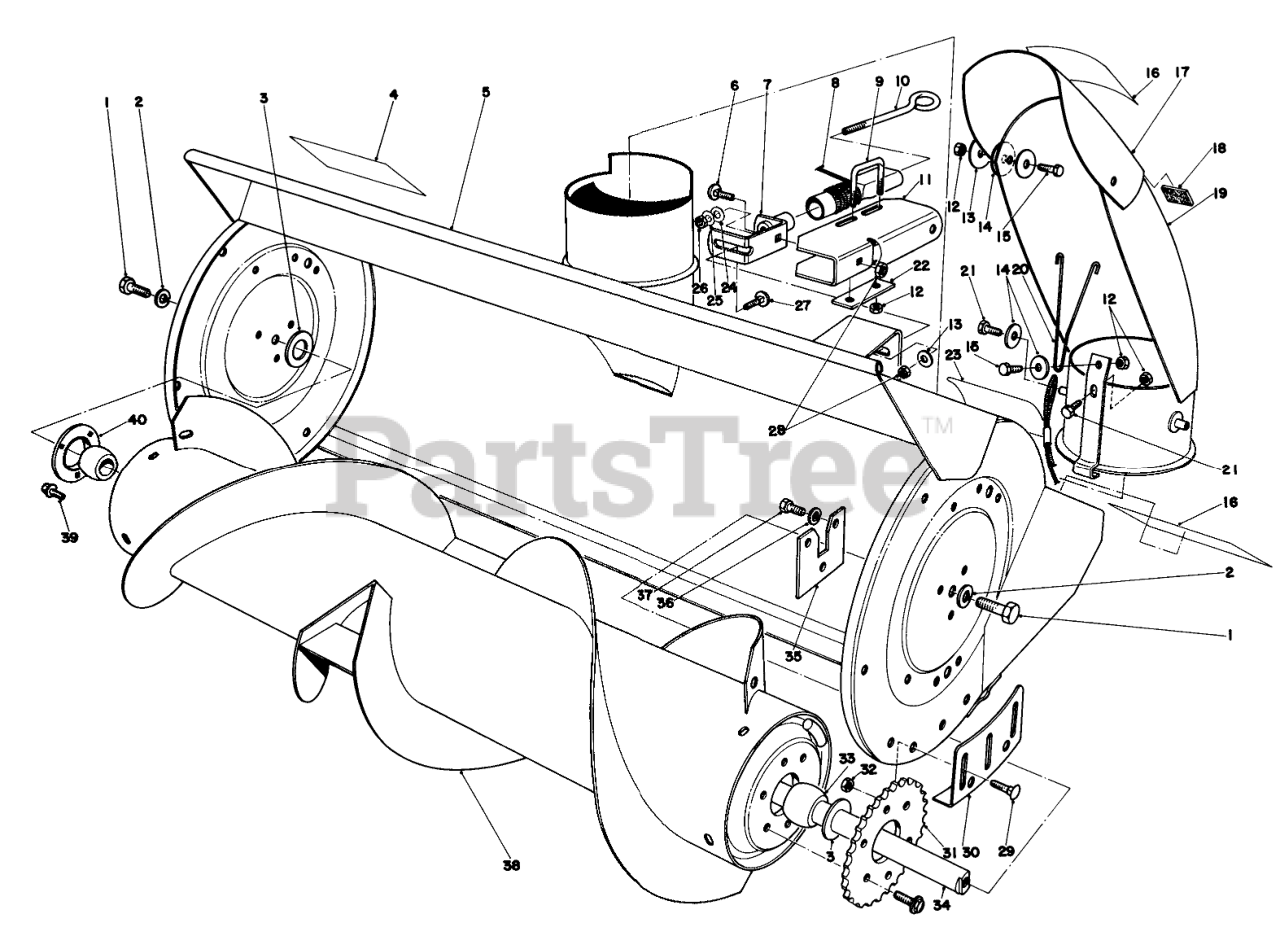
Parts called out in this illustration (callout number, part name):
1	SCREW-HH
2	WASHER-LOCK
3	Spring
4	DECAL
5	Header (Incl. Ref. #16 & 23)
6	SCREW-CARR
7	Bracket & Tube
8	Cable & Tube
9	U-Bolt
10	Eye Bolt
11	Shroud-Stack Drive
12	NUT-HEX, SIDE DEFORM
13	WASHER
14	Washer
15	SCREW-HH
16	Decal-Warning
17	Deflector (Incl. Ref. #16)
18	Molding-Deflector
19	Deflector Elbow
20	Hook-Lift Spring
21	SCREW-HH
22	Strap-Friction
23	CAUTION DECAL
24	WASHER-FLAT
25	Spring Washer
26	NUT-LOCK, CONE
27	BOLT-CARR
28	NUT-KEPS
29	Bolt
30	Skidshoe
31	Sprocket-Auger Drive
32	NUT-KEPS
33	AUGER SHAFT BRG
34	Shaft-Auger
35	Plate-Auger Mounting
36	WASHER-LOCK
37	SCREW-HH
38	Auger Assembly
39	Screw-Cap Hex. Hd.
40	Flangette
